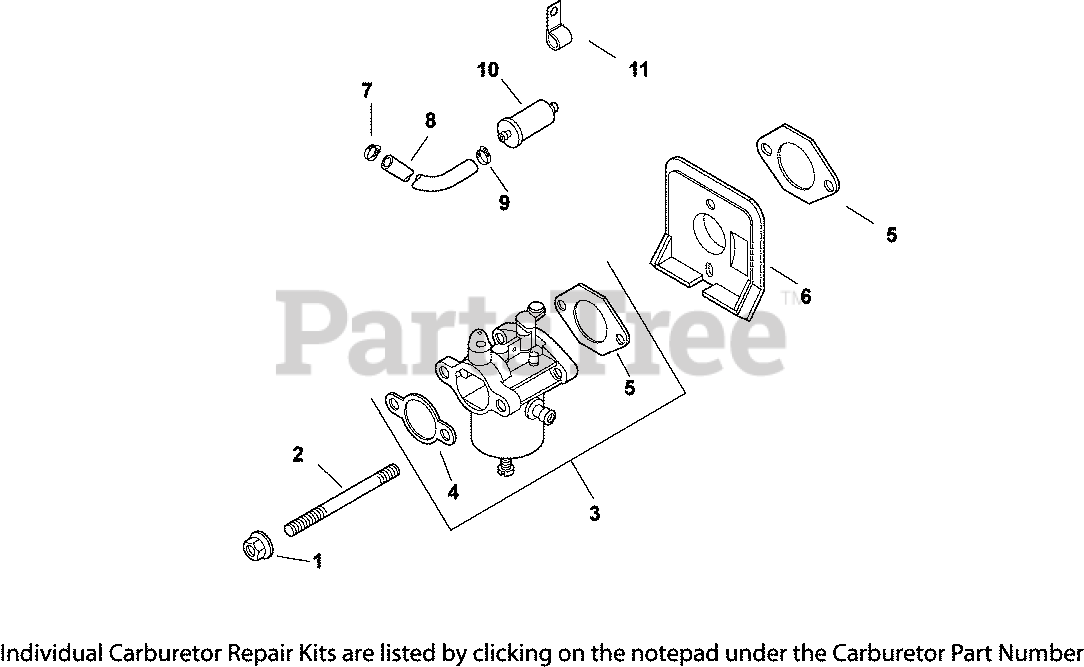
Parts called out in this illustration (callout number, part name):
1	NUT, FLG M6X1.0
2	STUD,M6X1.0X116
3	KIT, CARBURETOR w/GASKETS
4	GASKET, AIR CLEANER BASE
5	GASKET, CARBURETOR
6	DEFLECTOR, HEAT
7	CLAMP, BAND SPRING HOSE-(#2523737S)
8	HOSE,LW PERM.FUEL 24.00"-USE 25 111 81-S
9	CLAMP, HOSE (KM)-USE 25 237 31-S
10	FILTR,FUEL 75 MICRON (GRAVTY FEED)
11	CLIP, CABLE
